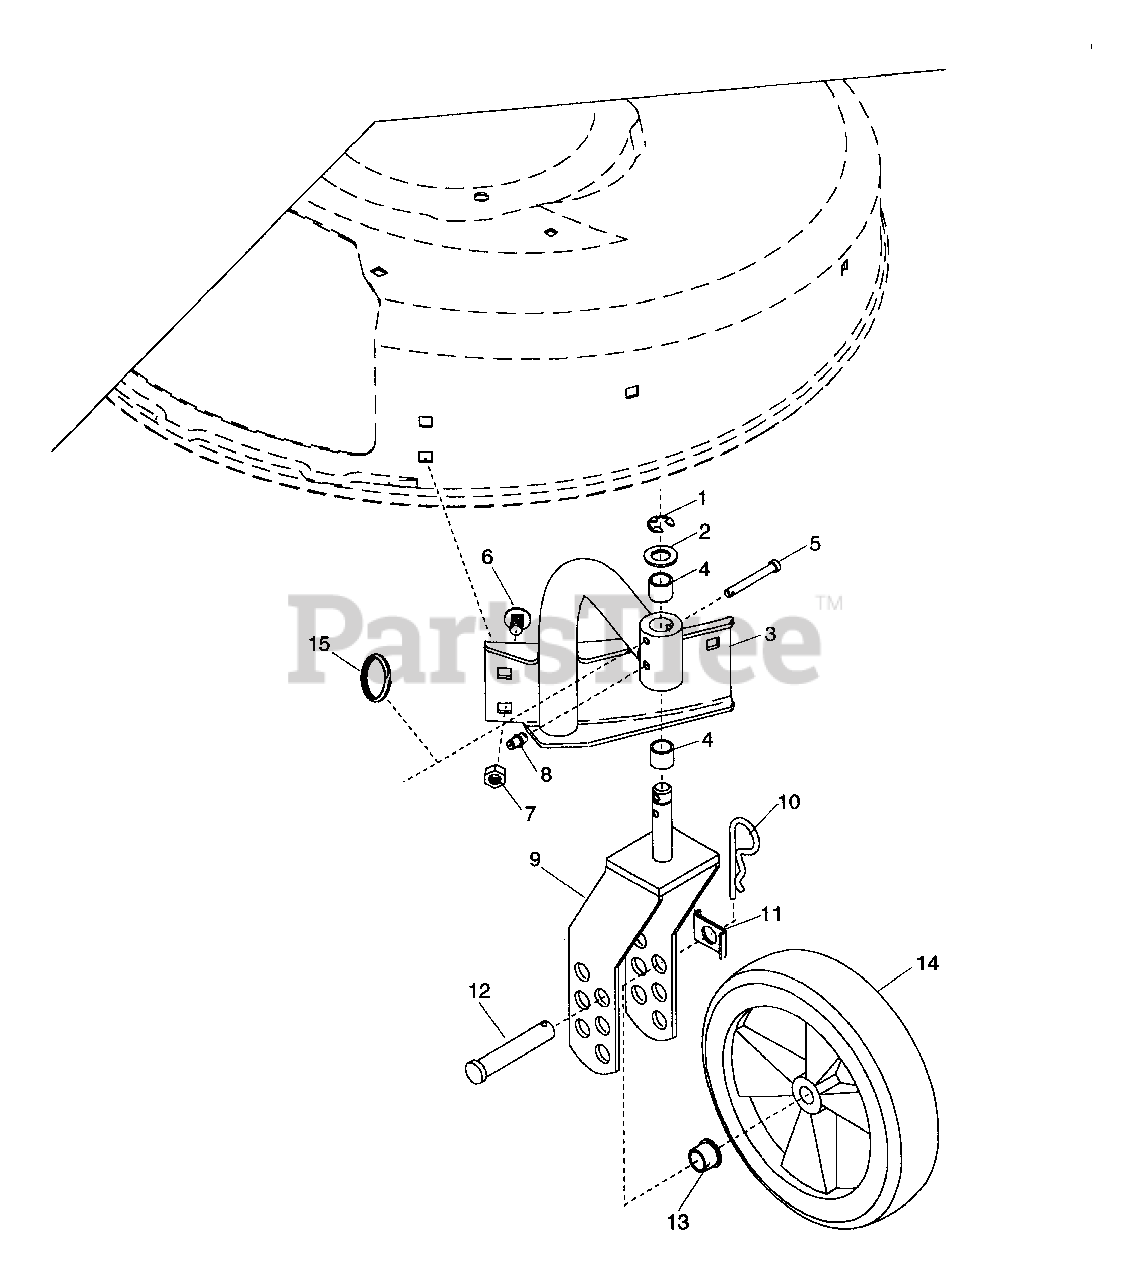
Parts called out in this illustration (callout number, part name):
1	RG-RTNG-EXT .625X.042
2	WSHR-FL-STL .630X1.005X.062 PL
3	RIGHT MOUNT ARM WELDMENT
4	BSHG-SLV .625X.750X.500 BR
5	PIN-CLEV .25X1.75
6	BLT-RDHDSQSHNK .31-18X.50 YZ
7	NUT-FLG. .312-18 PL
8	FTG-LUBE .25-28X.256 YWZC
9	WHEEL YOKE WELDMENT
10	PIN-HAIR INT .14X.4X2.75
11	AXLE TAB
12	PIN-CLEV .494X2.62 YWZC
13	BSHG-FLG .500X.625X.500X.750
14	WHEEL
15	KICKOUT RING YWZC
